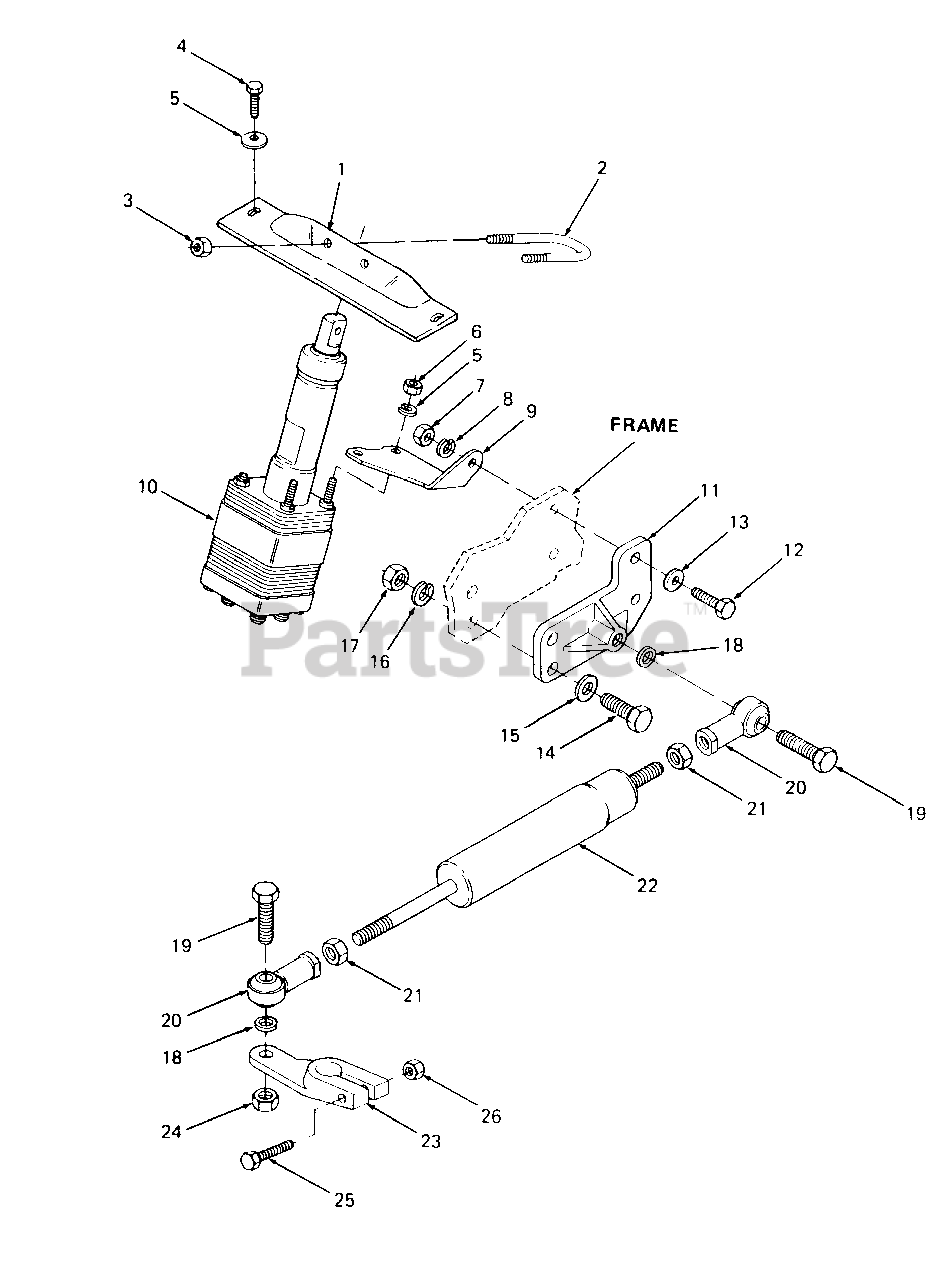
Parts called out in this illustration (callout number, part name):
1	Plate, Steering Support
3	Nut, Hex Center Lock, 5/16-24
4	Screw, Hex Cutting, 5/16-18 X .75 Lg
5	Washer, Bell, .345 X .88 X .060 Thk
6	Nut, Hex, 5/16-24 GR5
7	Nut, Hex Center Lock, 3/8-16 GR5
8	Washer, Lock, 3/8
9	Bracket, Power Steering Box Mtg
10	Power Steering Box w/Flat
13	Washer, Flat, .385 X .87 X .06 Thk HDN
14	Screw, Hex Cap, 1/2-13 X 1.25 Lg GR5
15	Washer, Flat, .51 X 1.12 X .06 Thk HDN
16	Washer, Lock, 1/2
17	Nut, Hex Center Lock, 1/2-13 GR5
18	Washer, Flat, .531 X .688 X .054 Thk
19	Screw, Hex Cap, 1/2-20 X 1.5 Lg GR5
20	Alignaball End, 1/2-20
21	Nut, Hex Jam, 1/2-20 GR5
24	Nut, Hex, 1/2-20 GR5
25	Screw, Hex Cap, 5/16-18 X 1.38 Lg GR5
26	Nut, Hex Center Lock, 5/16-18 GR5
